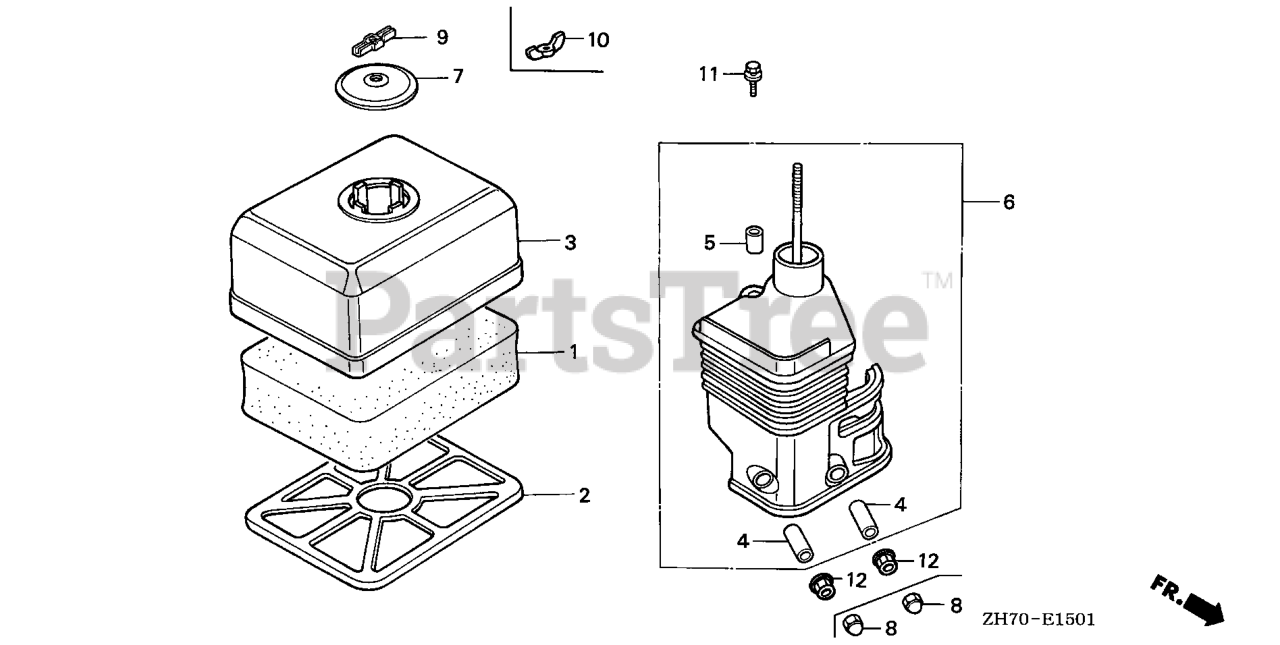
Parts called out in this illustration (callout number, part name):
1	ELEMENT, AIR CLEANER (SEMI-DRY)
2	GRID, AIR CLEANER (SEMI-DRY)
3	COVER, AIR CLEANER (SEMI-DRY)
4	COLLAR, AIR CLEANER
5	COLLAR B, AIR CLEANER
6	ELBOW, AIR CLEANER
7	CAP, CLEANER
8	NUT, CAP (6MM)
9	WINGNUT, AIR CLEANER COVER
9	WINGNUT (6MM)
10	WINGNUT, TOOL BOX SETTING
11	BOLT-WASHER (6X20)
12	NUT, FLANGE (6MM)
